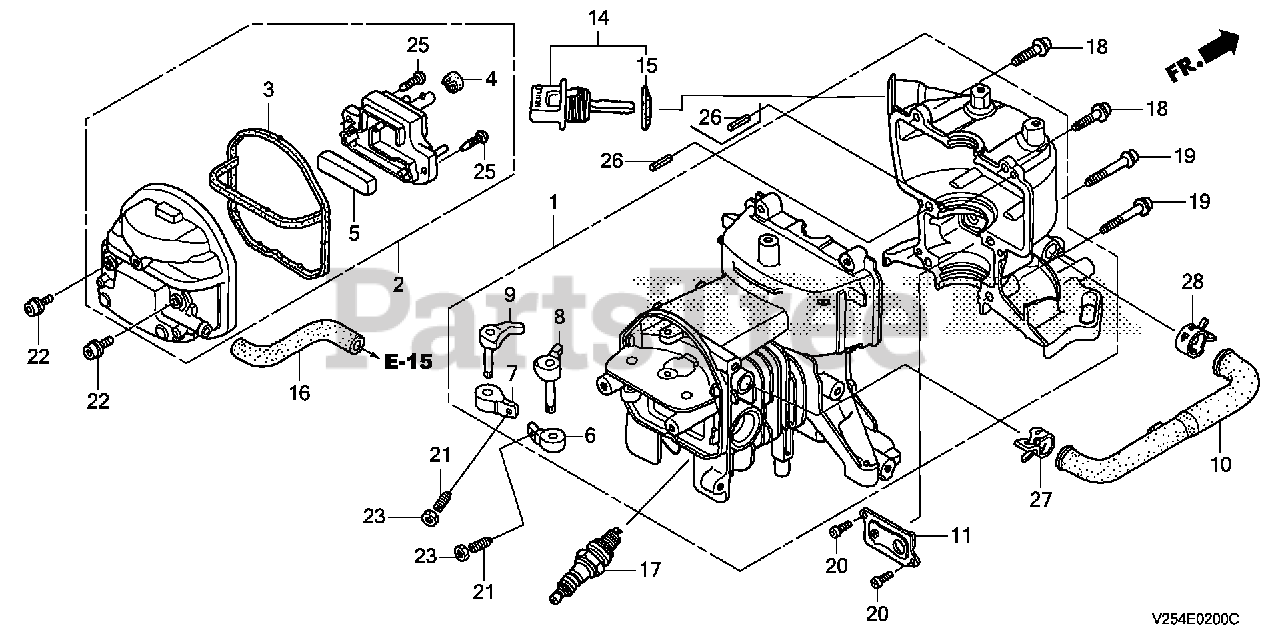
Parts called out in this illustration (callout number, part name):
1	CRANKCASE SET
2	COVER, CYLINDER HEAD
3	SEAL, HEAD COVER
4	GROMMET, HEAD COVER
5	FILTER, BREATHER
6	ARM, IN. VALVE ROCKER
7	ARM, EX. VALVE ROCKER
8	LIFTER, IN. VALVE
9	LIFTER, EX. VALVE
11	PLATE ASSY., OIL OUTLET VALVE
14	CAP ASSY., OIL FILLER
15	GASKET, OIL FILLER CAP
16	TUBE, BREATHER
17	SPARK PLUG (CMR4H) (NGK)
17	SPARK PLUG (CMR5H) (NGK)
17	SPARK PLUG (CMR6H) (NGK)
18	BOLT, SOCKET (5X20)
19	BOLT, SOCKET (5X30)
19	BOLT, SOCKET (5X32)
20	SCREW, PAN (4X8)
21	SCREW, TAPPET ADJUSTING
22	BOLT, SOCKET (5X12)
23	NUT, TAPPET ADJUSTING
25	SCREW, TAPPING (4X12)
26	PIN, SPRING (4X10)
27	CLAMP, TUBE (D12)
28	CLAMP, TUBE (D13)
